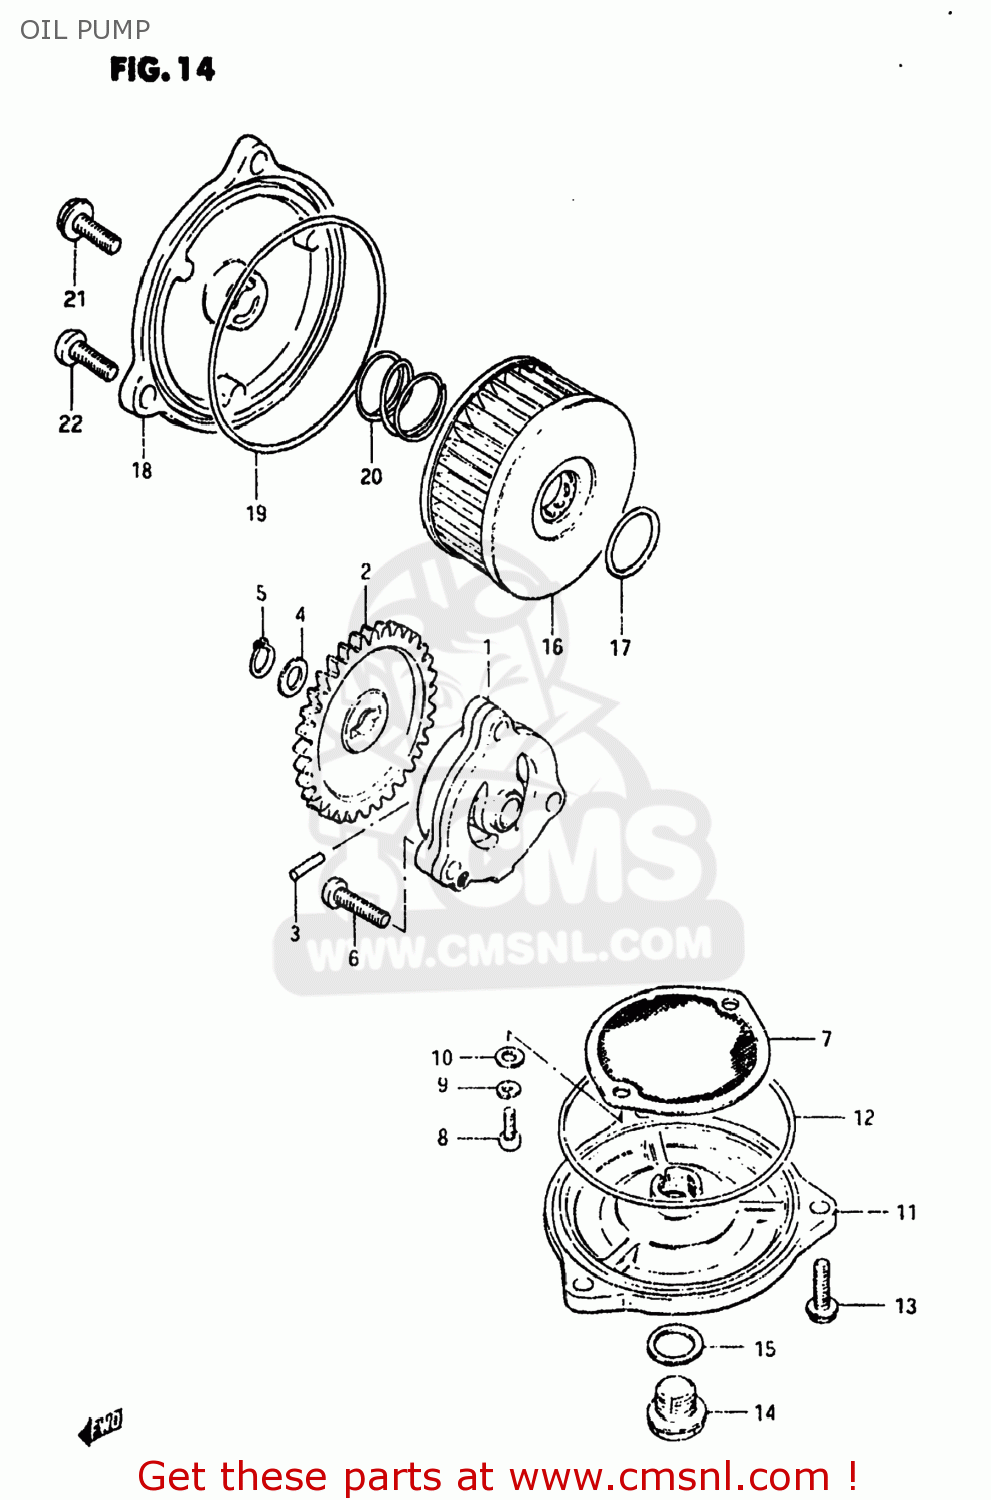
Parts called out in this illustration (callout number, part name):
1	PUMP ASSY,ENGINE OIL
2	GEAR,OIL PUMP DRIVEN(NT:33)
3	PIN(4X15.8)
4	SHIM
5	CIRCLIP
6	SCREW
7	STRAINER,ENGINE OIL
8	SCREW
9	LOCK WASHER
10	WASHER
11	CAP,OIL STRAINER
12	O RING(D:2.4,ID:85)
13	BOLT (6X20)
14	PLUG
15	GASKET(14X19.2X2) (NAS)
16	FILTER ASSY,ENGINE OIL
17	O RING(D:2.4,ID:15.8)
18	CAP,OIL FILTER
19	O RING(D:2.4,ID:73)
20	SPRING
21	BOLT (6X20)
22	SCREW
